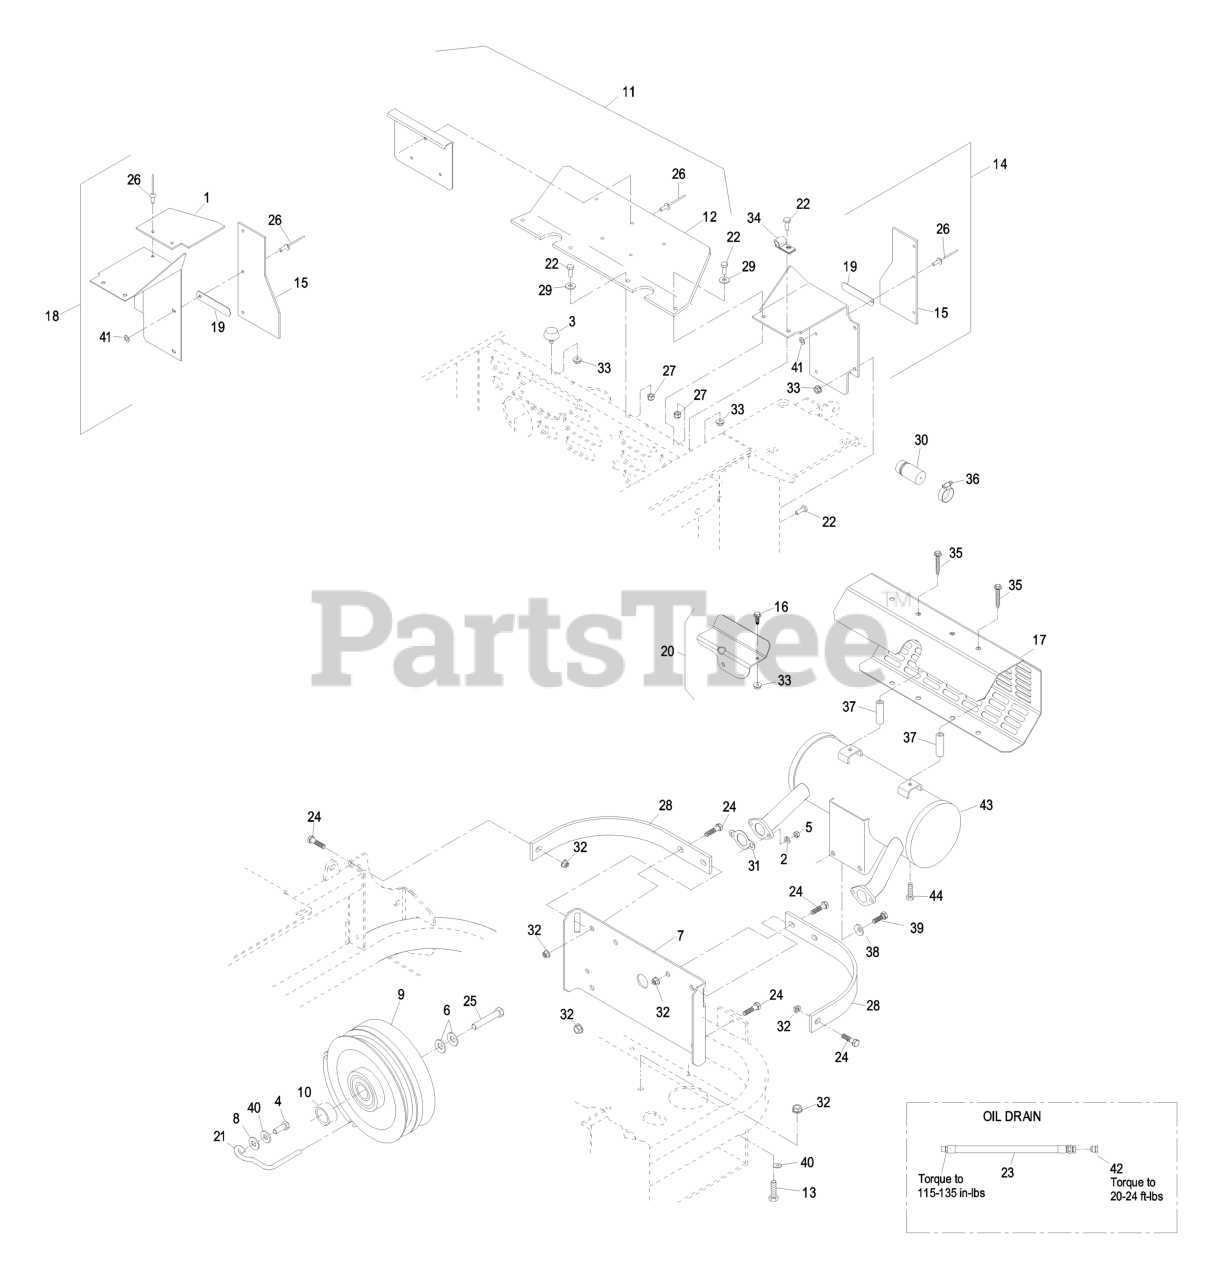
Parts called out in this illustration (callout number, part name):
1	BAFFLE-COOLER, ENGINE
2	WASHER-LOCK
3	BUMPER-RUBBER
4	SCREW-HH
5	NUT-HEX
6	WASHER-SPRING
7	GUARD-CLUTCH
8	WASHER-FLAT
9	KIT-CLUTCH
10	SPACER-CLUTCH
11	SHIELD ASM
12	SHIELD-ENGINE
13	SCREW-HH
15	SHIELD-ENGINE
16	SCREW-HH
17	GUARD-MUFFLER
18	RH SHIELD ASM
19	CLIP-BAFFLE, REAR
20	CABLE HEAT SHIELD KIT
21	ROD-BELT
22	SCREW-HH
24	SCREW-HH
25	SCREW-HH
26	RIVET-POP
27	NUT-LOCK, NI
28	STRAP-GUARD
29	WASHER-FLAT
30	ARRESTER-SPARK
32	NUT-HHF, WHIZ
34	CLIP-LOOM
35	SCREW-HWH
36	CLAMP-MUFFLER
38	SCREW-HH
39	SCREW-HH
40	WASHER-BELLEVILLE
41	WASHER-FLAT
43	KIT,MUFFLER KOHLER
